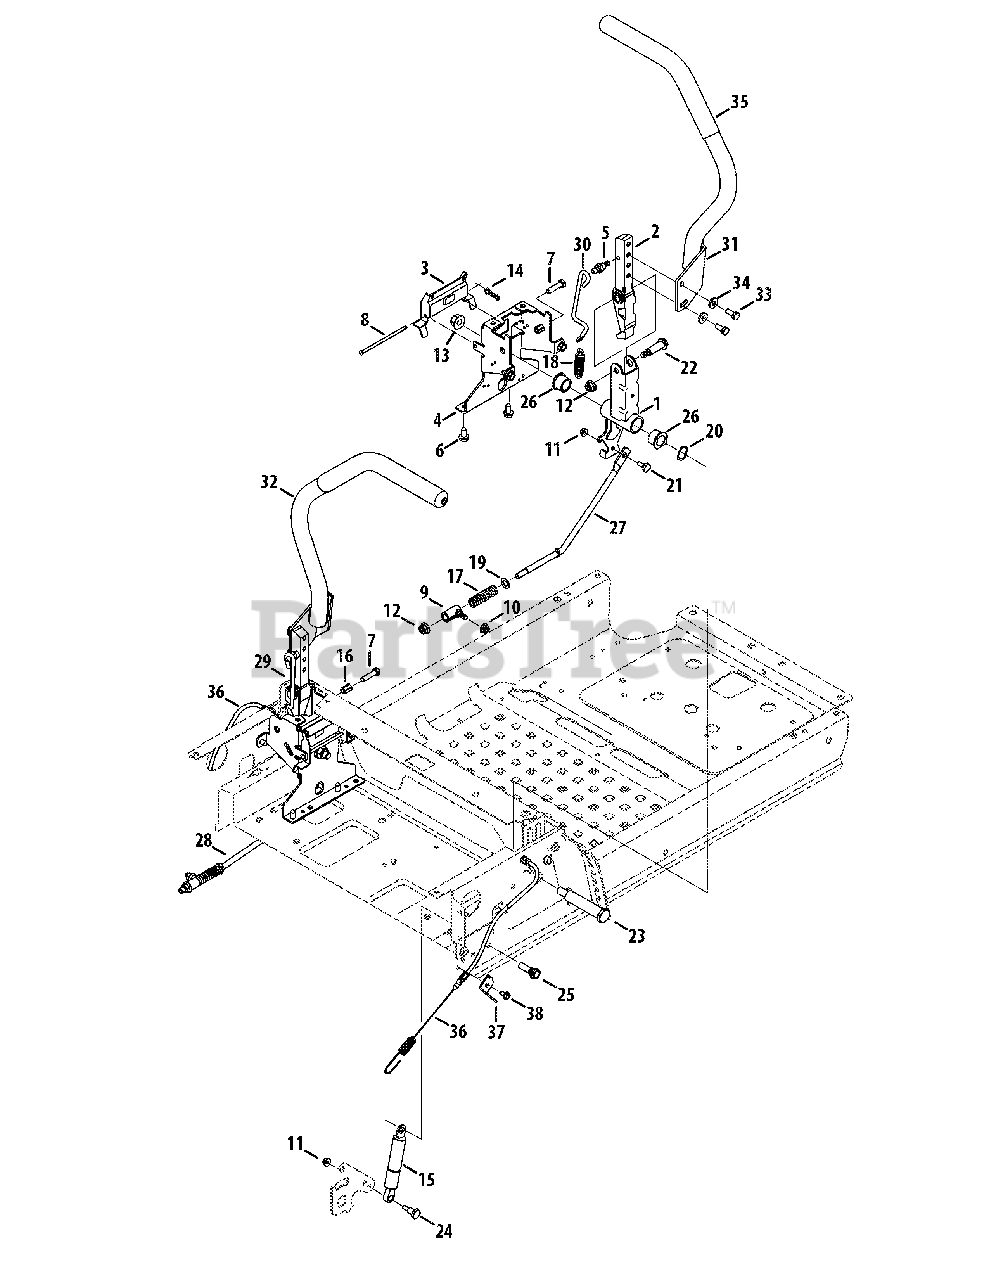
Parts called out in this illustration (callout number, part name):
1	Lap Bar Pivot Hub Assembly
2	Lower Arm Asembly
3	Brake Cable Actuator Lever
4	Lap Bar Pivot Support Bracket
5	Shoulder Screw, 5/16-18 x .48
6	Hex Washer Screw, 5/16-18 x .750
7	Hex Screw, 5/16-18 x 1.25
8	Pin, .188 x 4.1
9	Shoulder Ferrule, 3/8 x .420
10	Flange Lock Nut, 5/16-18
11	Flange Lock Nut, 1/4-20
12	Flange Lock Nut, 3/8-16
13	Flange Lock Nut, 1/2-13
14	Cotter Pin
15	Dampener Cylinder, .87 x 7.06
16	Lock Nut Rivet, 5/16-18
17	Compression Spring
18	Extension Spring, .560 x 2.31250 x .105
19	Flat Washer, .385 x .62 x .063
20	Wave Washer, .785 x 1.00 x .012
21	Shoulder Screw, .375 x .181
22	Shoulder Screw, .498 x 1.290
23	Shoulder Bolt, 1/2-13 x .75 x 3.25
24	Shoulder Screw, .395 x .56
25	Shoulder Screw, .395 x .83
26	Flange Bearing, .75 x 1.00 x .73
27	RH Hydro Control Rod
28	LH Hydro Control Rod
29	LH Detent Rod
30	RH Detent Rod
31	RH Lapbar Lever Assembly
32	LH Lapbar Lever Assembly
33	Hex Screw, 5/16-18 x .75
34	Flat Washer, .344 x .750 x .120
36	Parking Brake Cable
37	Parking Brake Cable Bracket
38	Hex Washer Screw, 1/4-20 x.500
